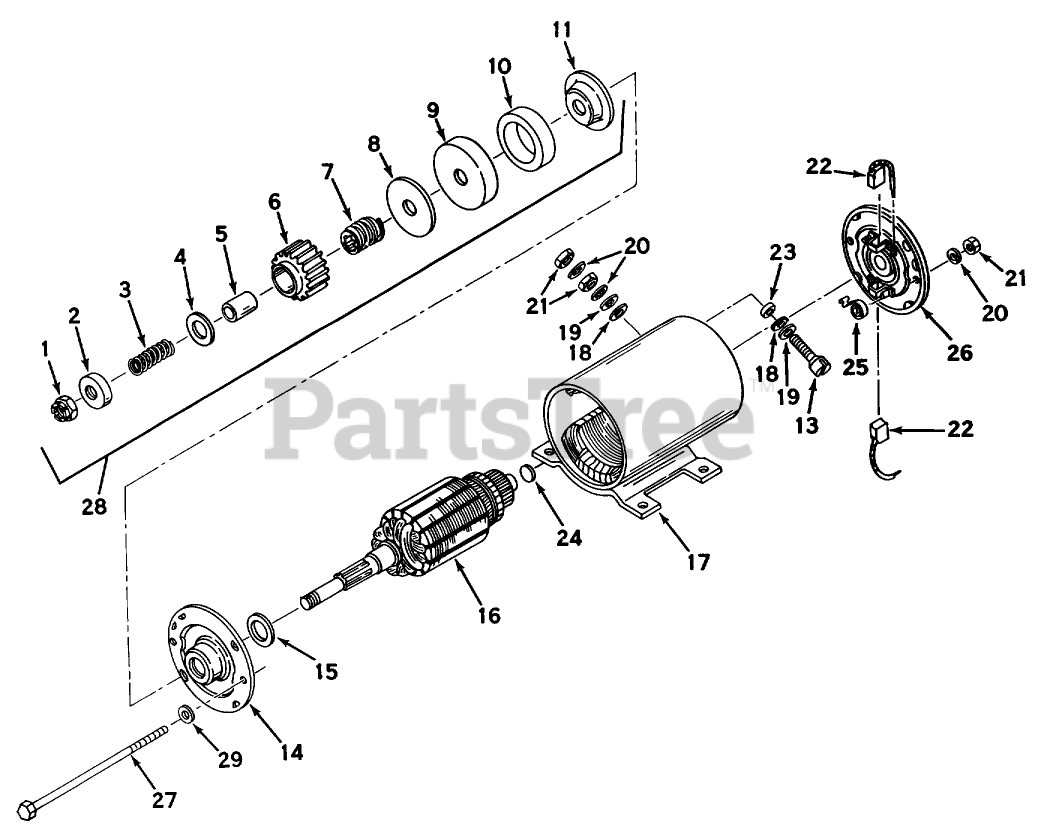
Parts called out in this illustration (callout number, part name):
1	Nut, Hex
2	Setscrew
3	Spring, Anti drift
4	Washer, Pinion
5	Sleeve, Anti drift
6	Gear, Pinion
7	Shaft, Screw
8	Washer, Thrust
9	Cup, Cushion
10	Cushion, Rubber
11	Washer, Thrust
13	Bolt, Terminal
14	Cap Assy., Drive end (Incl. Bearing)
15	Washer, Spacing (.024 Thick)
15	Washer, Spacing (.008 Thick)
16	Armature
17	Housing Assy. (Incl. pole shoes, field coils, terminal post, straight mounting bracket, Nos. 18 thru 21)
18	Washer, Insulating
19	Washer
20	Washer, Lock
21	61710/VAR.HILLER AT
22	Brush Spring Kit
23	Bushing, Insulating
24	Washer, Spring
25	Spring, Brush
26	End Cap Assy., Commutator
27	Bolt, Thru
28	Drive Assy., Complete (Incl. Nos. 1 thru 11)
29	Washer
